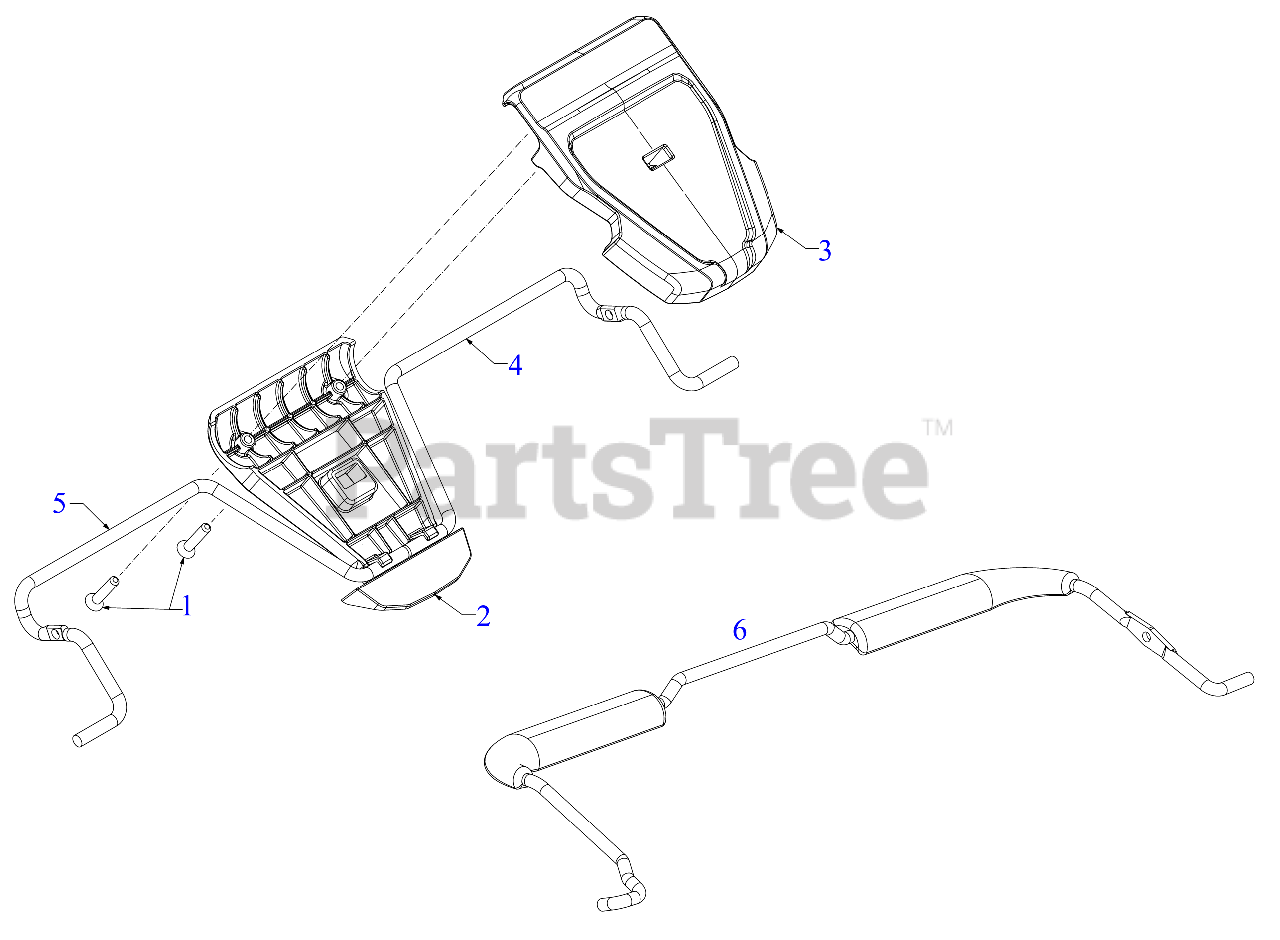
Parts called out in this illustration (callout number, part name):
1	SCREW #10-16 x 1.00
2	LOWER CONTROL HOUSING DOUBLE BAIL
3	UPPER CONTROL HOUSING DOUBLE BAIL
4	DRIVE BAIL (LH)
5	DRIVE BAIL (RH)
6	OPERATOR BAIL ASSEMBLY
